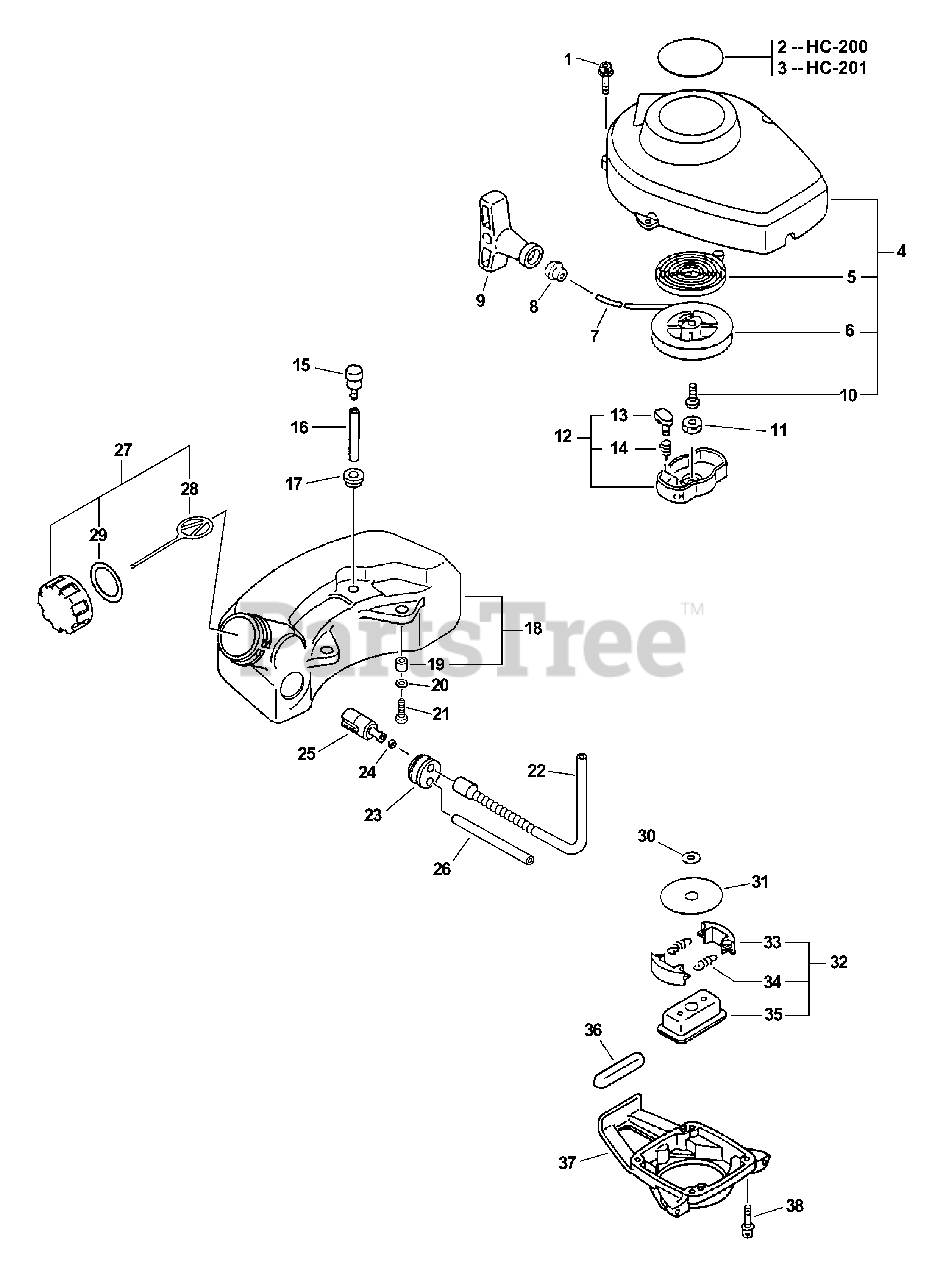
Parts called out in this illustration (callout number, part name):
1	SCREW - 4X16
2	LABEL - MODEL HC-200
3	LABEL - MODEL HC-201
4	STARTER ASSY
5	SPRING, REWIND
6	REEL, ROPE
7	ROPE, STARTER - 3.5X1000
8	GUIDE, ROPE
9	GRIP, STARTER
11	NUT - LEFT HAND
12	STARTER PAWL ASSY
13	PAWL, STARTER - BLACK
14	SPRING, RETURN
15	VENT, FUEL TANK
16	PIPE - 3X6X35 -- BLACK
17	GROMMET
18	TANK, FUEL
20	WASHER - 5
21	SCREW - 5X16
22	PIPE, FUEL - CORRUGATED
23	GROMMET
24	CLIP - 6
25	FILTER, FUEL
26	PIPE - 3X6X110 -- CLEAR
27	CAP ASSY - ORANGE
28	CONNECTOR, CAP
29	GASKET, CAP
30	WASHER, CLUTCH
31	PLATE, CLUTCH
32	CLUTCH ASSY
33	SHOE, CLUTCH
34	SPRING, CLUTCH
35	HUB, CLUTCH
36	CUSHION, FUEL TANK
37	CASE, CLUTCH
38	SCREW - 4X16
